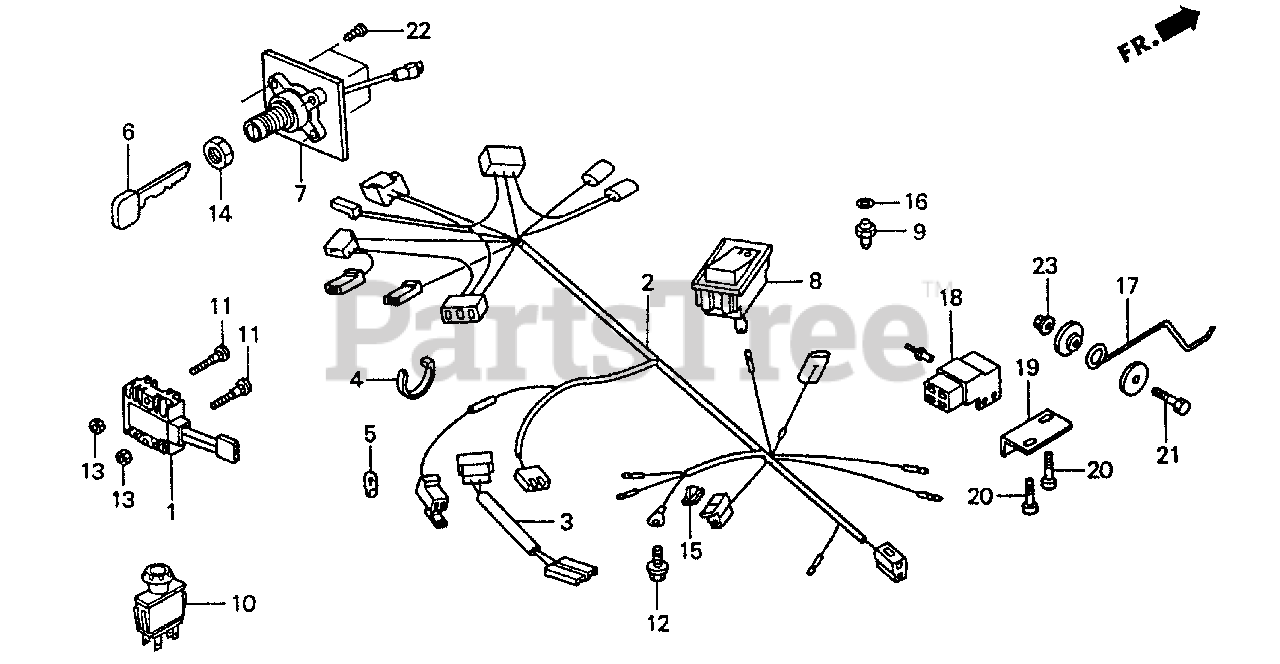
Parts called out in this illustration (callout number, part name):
1	RECTIFIER ASSY., REGULATOR (20A)
2	WIRE HARNESS ASSY., MAIN
3	SUB-WIRE HARNESS ASSY.
4	TIE, CABLE
6	KEY, COMBINATION SWITCH
7	SWITCH ASSY., MAIN
8	SWITCH ASSY., LIGHTING
9	SWITCH ASSY., NEUTRAL
10	SWITCH ASSY., P.T.O. CLUTCH
10	SWITCH ASSY., P.T.O. CLUTCH (AM12793)
11	BOLT, HEX. (6X25)
12	BOLT, FLANGE (6X12)
13	NUT, FLANGE (8MM)
14	NUT, KNURLED
15	CLIP, WIRE
16	O-RING, WIRING
17	LEVER, SWITCH (M133666)
18	SWITCH, BRAKE LIGHT (AM108483)
19	BRACKET, REVERSE (MT132262)
20	SCREW, HEX. (5/16-18)
21	BOLT (8X35) (03M7187)
22	SCREW, TAPPING (#8-32)
23	NUT D, LOCK (8MM)
